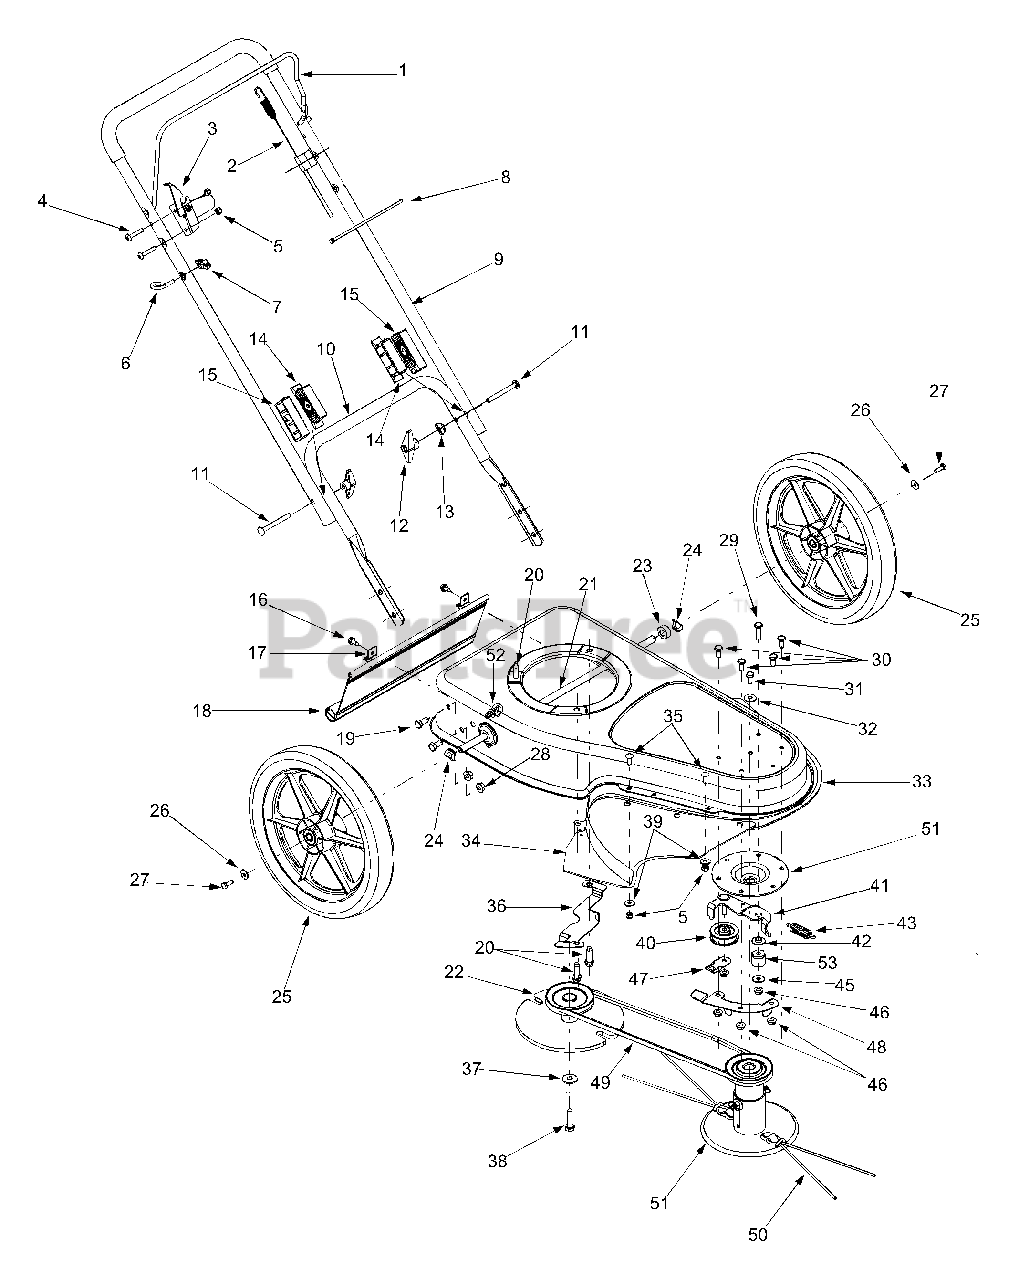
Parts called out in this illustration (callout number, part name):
2	Engagement Cable
3	Control Lock Bracket
4	Machine Screw 1/4-20 x 1.50
5	Hex Lock Nut 1/4-20
6	Eye Bolt 1/4-20
8	Cable Tie
13	Shoulder Washer.320 ID x.93 OD
14	Lower Handle Connector
15	Upper Handle Connector
16	Hex Washer Screw 1/4-20 x.625
17	Trail Shield Clip
18	Trail Shield
19	Hex Cap Screw 3/8-16 x.750
20	Hex Washer Screw 3/8-16 x 1.25
21	Trimmer Axle
22	Flywheel / Pulley Combination
23	Spacer.51 ID x 1.0 OD
24	Spacer Washer.501 ID x 1.0 OD
25	Wheel Assembly
26	Bell Washer.265 ID x.75 OD
27	Hex Cap Screw 1/4-20 x.75
28	Flange Lock Nut 3/8-16
29	Screw 5/16-18 x 2.25
30	Screw 5/16-18 x.75
31	Hex Cap Screw 5/16-24 x.625
32	Bell Washer.325 ID x.930 OD
35	Hex Carriage Screw 1/4-20 x.75
38	Hex Cap Screw 3/8-24 x 1.50
39	Flat Washer.28 ID x.74 OD
40	Idler Pulley
41	Idler Bracket Assembly
42	Idler Spacer
43	Extension Spring.50 Dia x 1.88 Lg
45	Flat Washer
46	Flange Lock Nut 5/16-18
49	V-Belt
50	Trimmer Line.155 (Incl. 10 pieces)
51	Spindle Assembly
52	Cable Retainer Clip
53	Spacer
